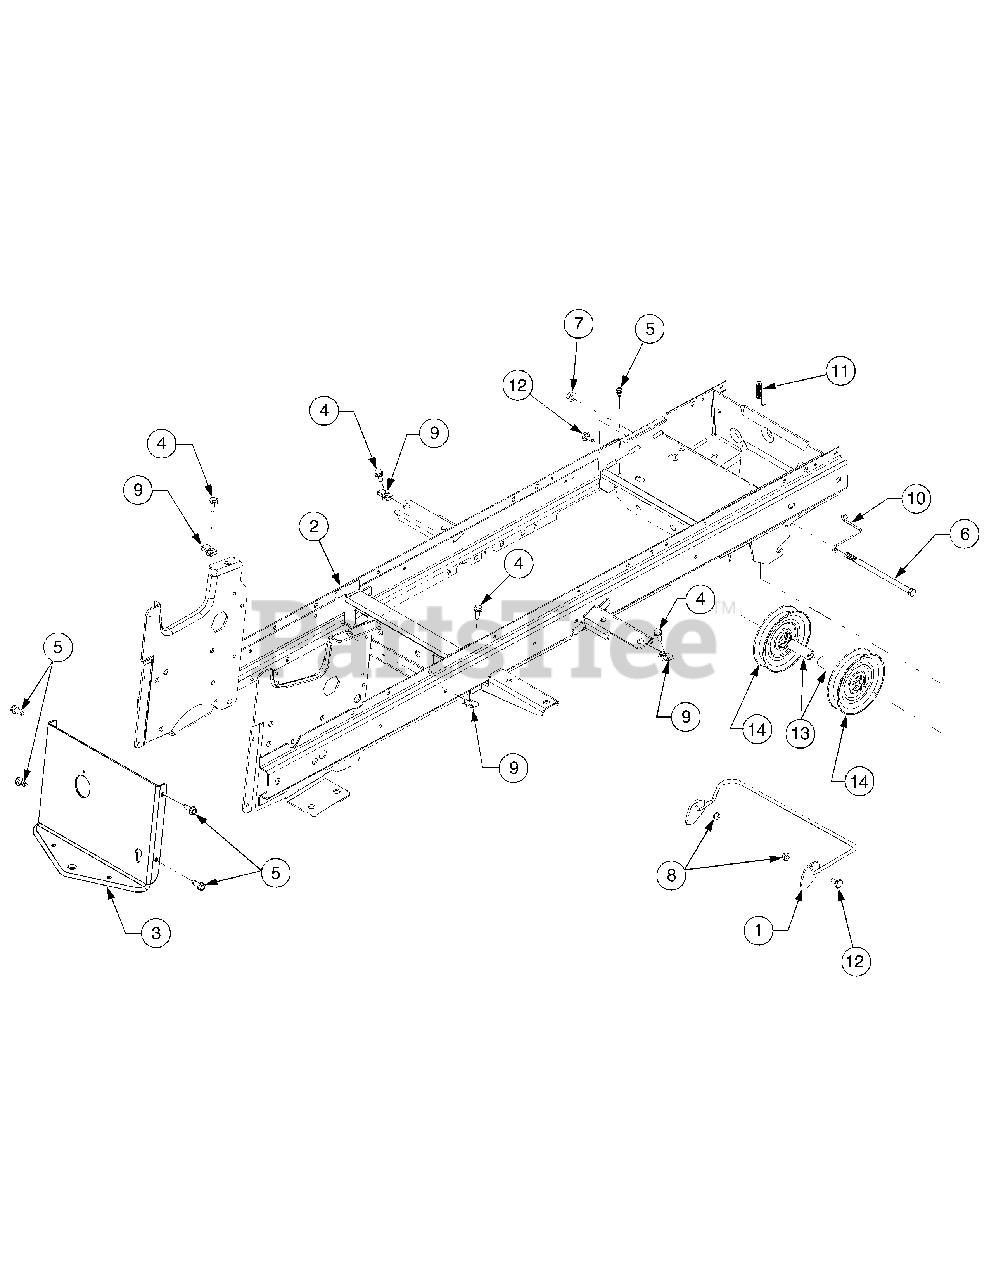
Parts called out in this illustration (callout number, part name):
4	Screw, Hex Wsh Hd Tapp 5/16-18 x 1.0
5	Screw, Hex Wsh Hd Tap 5/16-18 x .75
6	Screw, Hex Cap, 3/8-16 x 7.0
7	Nut, Hex Flange Lock, 3/8-16
8	Nut, Hex Flange Lock, 1/4-20
9	U-Nut, 5/16-18
10	Belt Guide
11	Spring, Latch
12	Bolt, Shoulder
13	Spacer, Idler, .411 x .720 x 2.19
14	Pulley, Idler
